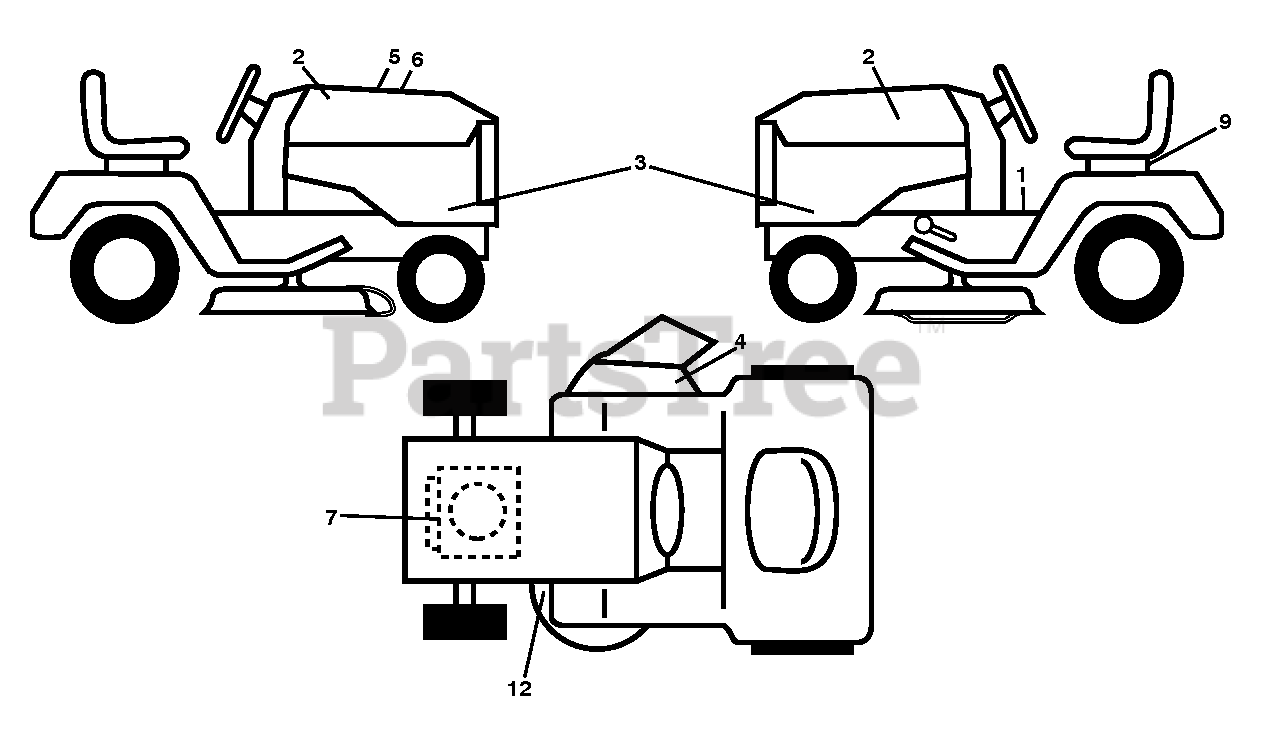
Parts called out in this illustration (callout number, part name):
1	DECAL.FENDER.WARNING.ENGLISH
2	DECAL.BADGE.170MM.TEXTLOGO.
3	DECAL.SIDE.PANEL.YTH22V46.2013
4	DECAL.MOWER.WARN.KEEP.HAND.AWY
5	DECAL.WARNING.CUST.RESP.E85.
6	DCL.RPL.BSM44.INTK.TLW.46.K46
7	DECAL.ENG.BS.22INTK.DOM.381708
9	DECAL BTRY SYMBOLS
12	DECAL.V-BELT.SCH.42/46"MEC/ELE
